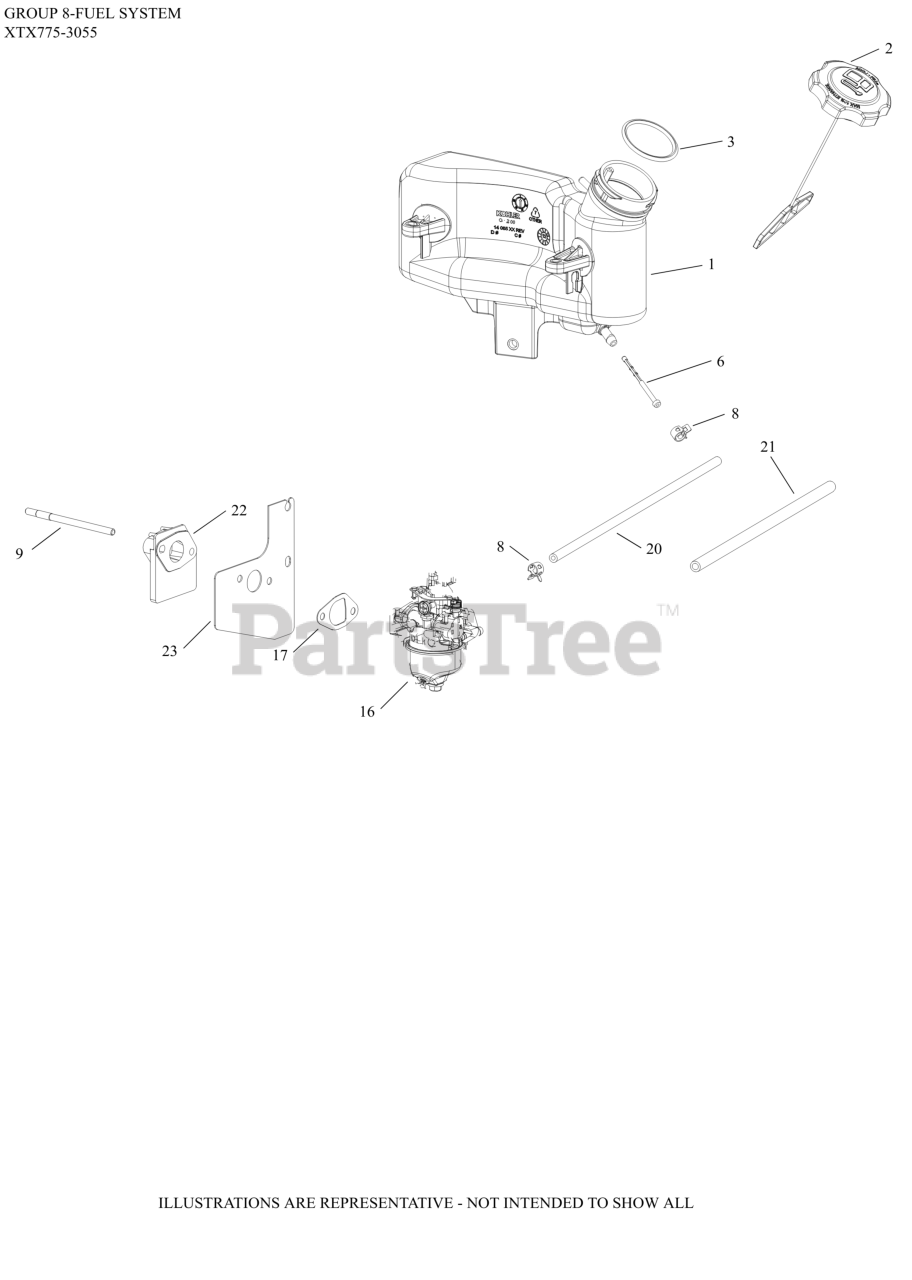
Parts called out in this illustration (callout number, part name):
1	TANK, FUEL
2	CAP ASSEMBLY, FUEL
3	SEAL, FUEL CAP
6	FILTER, FUEL IN-NIPPLE
8	CLAMP, HOSE (NON-CALIF)(#1423710S)
9	STUD,M6X1.0X100.2MM
16	KIT, CARBURETOR 13 MM STD CHOKE
17	KIT, INTAKE GASKET
20	HOSE, EVAPORATIVE
21	HOSE, FUEL LOW-PERMEATION
22	KIT, SPACER
23	GASKET, CARBURETOR
NI	KIT, HIGH ALTITUDE - USE 14 755 04-S
NI	KIT, CARBURETOR REPAIR (RUIXING)
